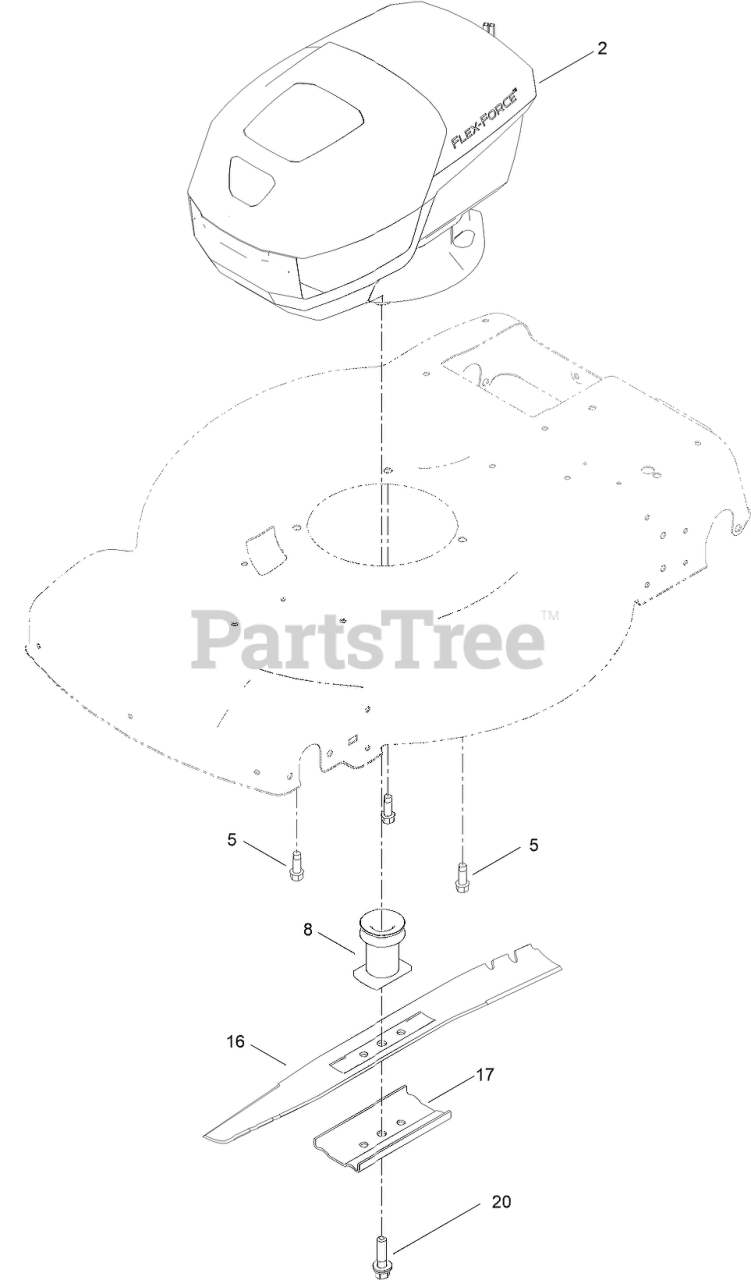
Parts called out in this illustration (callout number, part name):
2	MOTOR MODULE 60V
5	SCREW-THD FORM, HWH
8	DRIVER-BLADE
16	BLADE [BLACK]
17	SUPPORT-BLADE
20	BOLT-BLADE
